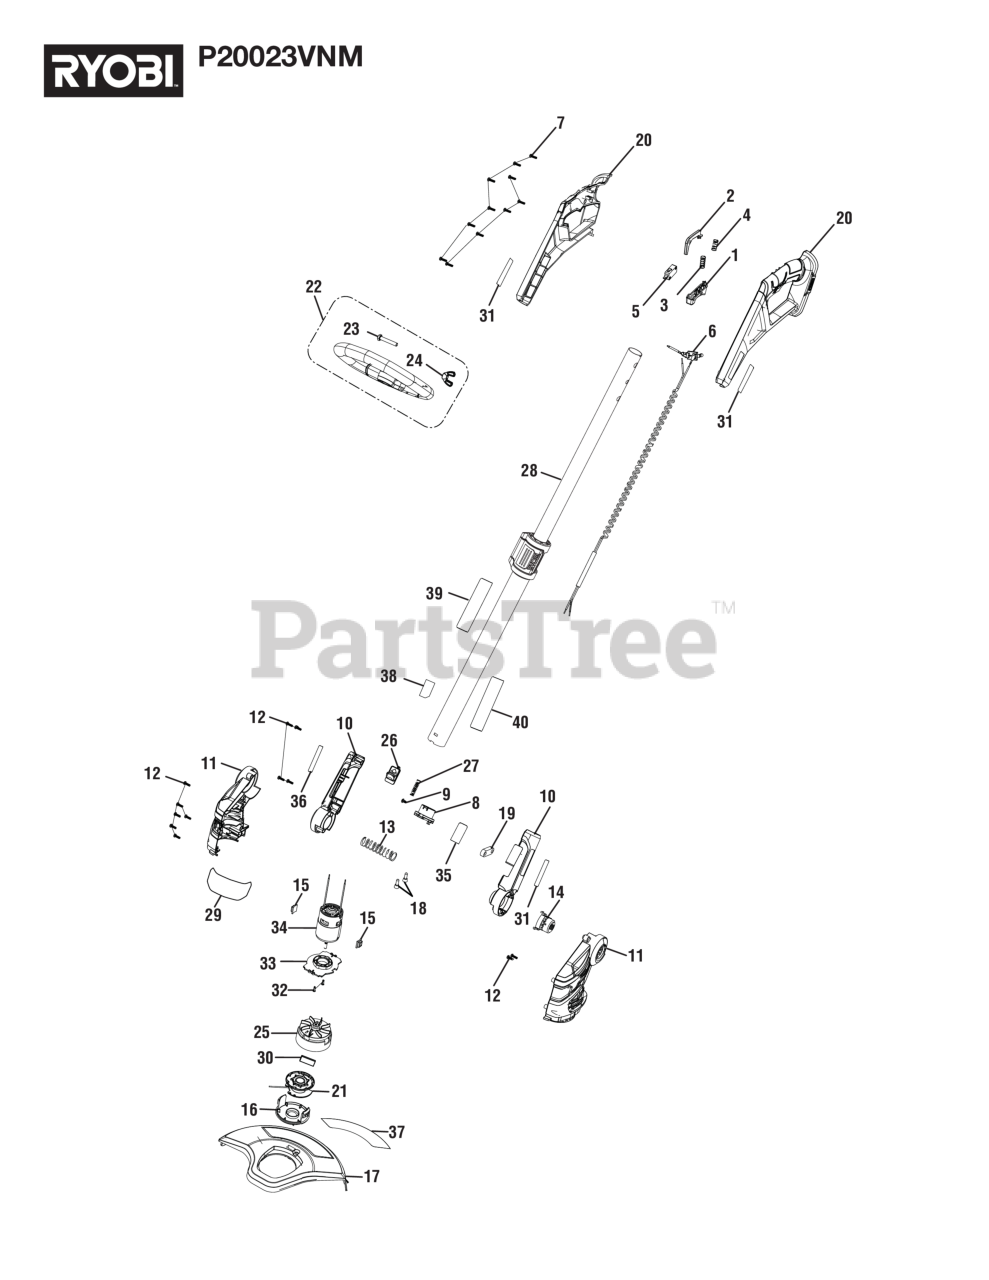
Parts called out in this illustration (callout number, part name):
1	Switch Trigger
2	Trigger Lock-Out Button
3	Compression Spring
4	Compression Spring
5	Micro Switch
6	Wire and Contact Plate Assembly
7	Screw (M3.5 x 14 mm, Pan Hd.)
8	Lower Tube Bushing
9	Screw (M4x 7 mm, T20 Torx Hd)
10	Shaft Coupler Assembly
11	Motor Housing Assmbely
12	Screw (M4 x 12 mm, Pan Hd.)
13	Pivot Button Spring
14	Pivot Button
15	Rubber Bumper
16	Spool Cap (AC14HC)
17	Guard Assembly
18	Wire Connector (Closed End)
19	Wire Press Plate
20	Rear Handle Assembly
21	Spool Assembly
22	Auxiliary Handle Assembly
23	Bolt (1/4-20 x 45 mm, Cap Hex Hd.)
24	Wing Nut (1/4-20, Plastic)
25	Spool Base & Slider Assembly
26	Edger Button
27	Edger Button Spring
28	Telescoping Shaft Assembly
29	Logo Label
30	BALANCE PLATE
31	Logo Label
32	Screw (T25 x 12 mm, Flange Hd.)
33	Motor Mounting Plate
35	Pull to Edge Label
37	Autofeed Label
39	Warning Icon Label
40	Warning Label (French/Spanish)
